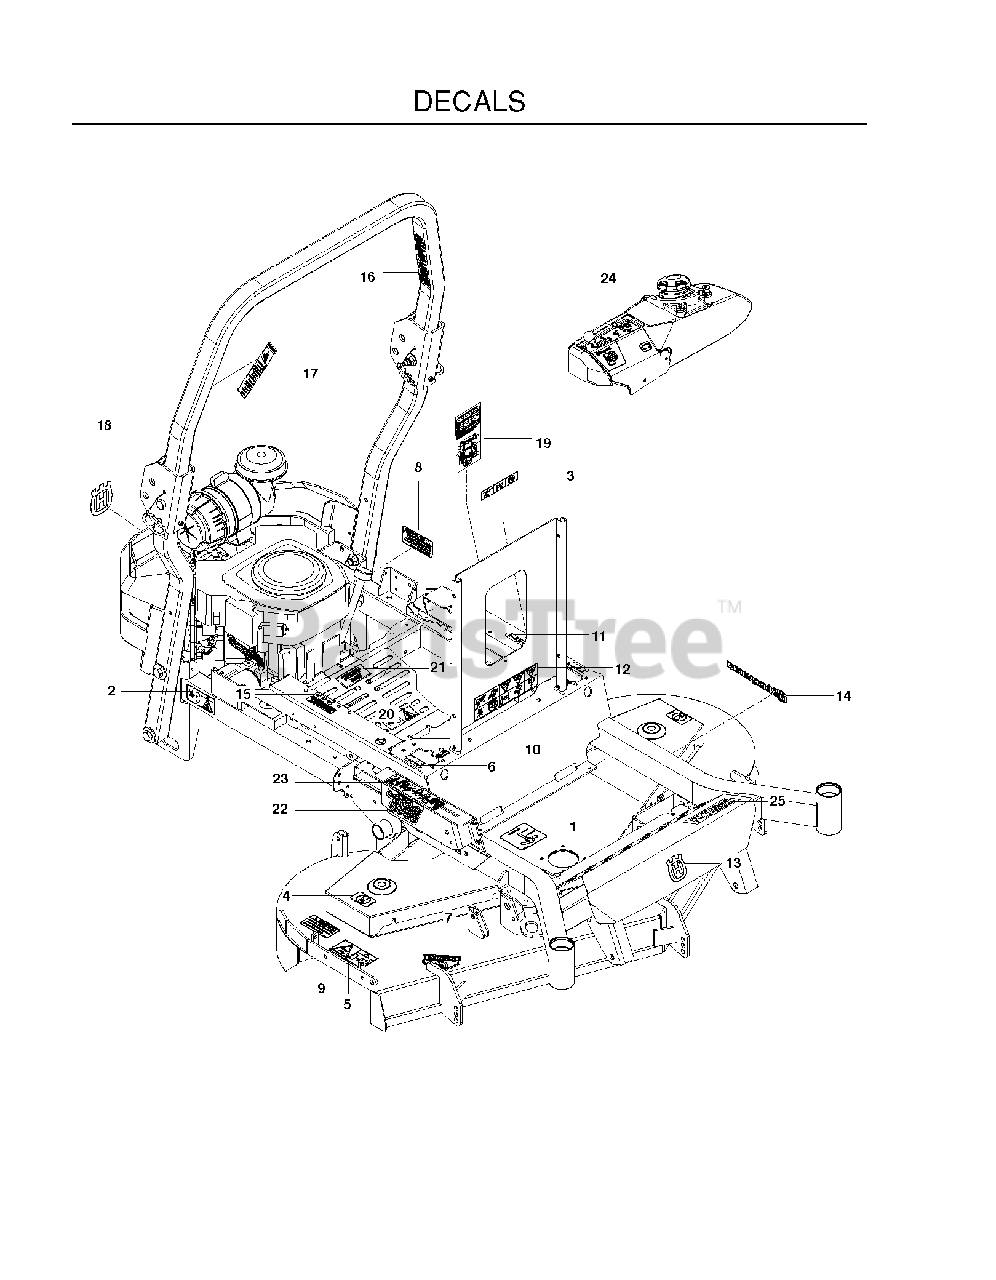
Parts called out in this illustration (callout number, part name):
1	DECAL, BELT ROUTING
2	DECAL, BELT DRIVE
3	EURO DECAL-BATTERY WARNIN6
4	DECAL, NO STEP
5	DECAL, EURO SEVERING
6	DECAL, MOTION CONTROL
7	DECAL, CPSC
8	DECAL, PROP. 65
9	DECAL, CAUTION
10	DECAL, F.S.T.
11	DECAL, PARK BRAKE
12	DECAL, WARNING
13	DECAL.AUGER.HUSQ.CROWN.SNOW
14	RP.DECAL.BADGE.170MM.TEXTLOGO
15	DECAL, FUSE
16	DECAL, ROPS
17	DECAL, ROPS, WARNING
18	DECAL, CROWN H, 110MM
19	DECAL, SERVICE
20	DECAL, WARNING SPARK ARRESTOR
21	HG_DECAL, ZT-3400
22	DECAL, HEIGHT
23	DECAL, RELEASE LEVER
24	DECAL, CONTROL, GAS
25	DECAL, P-ZT5224
